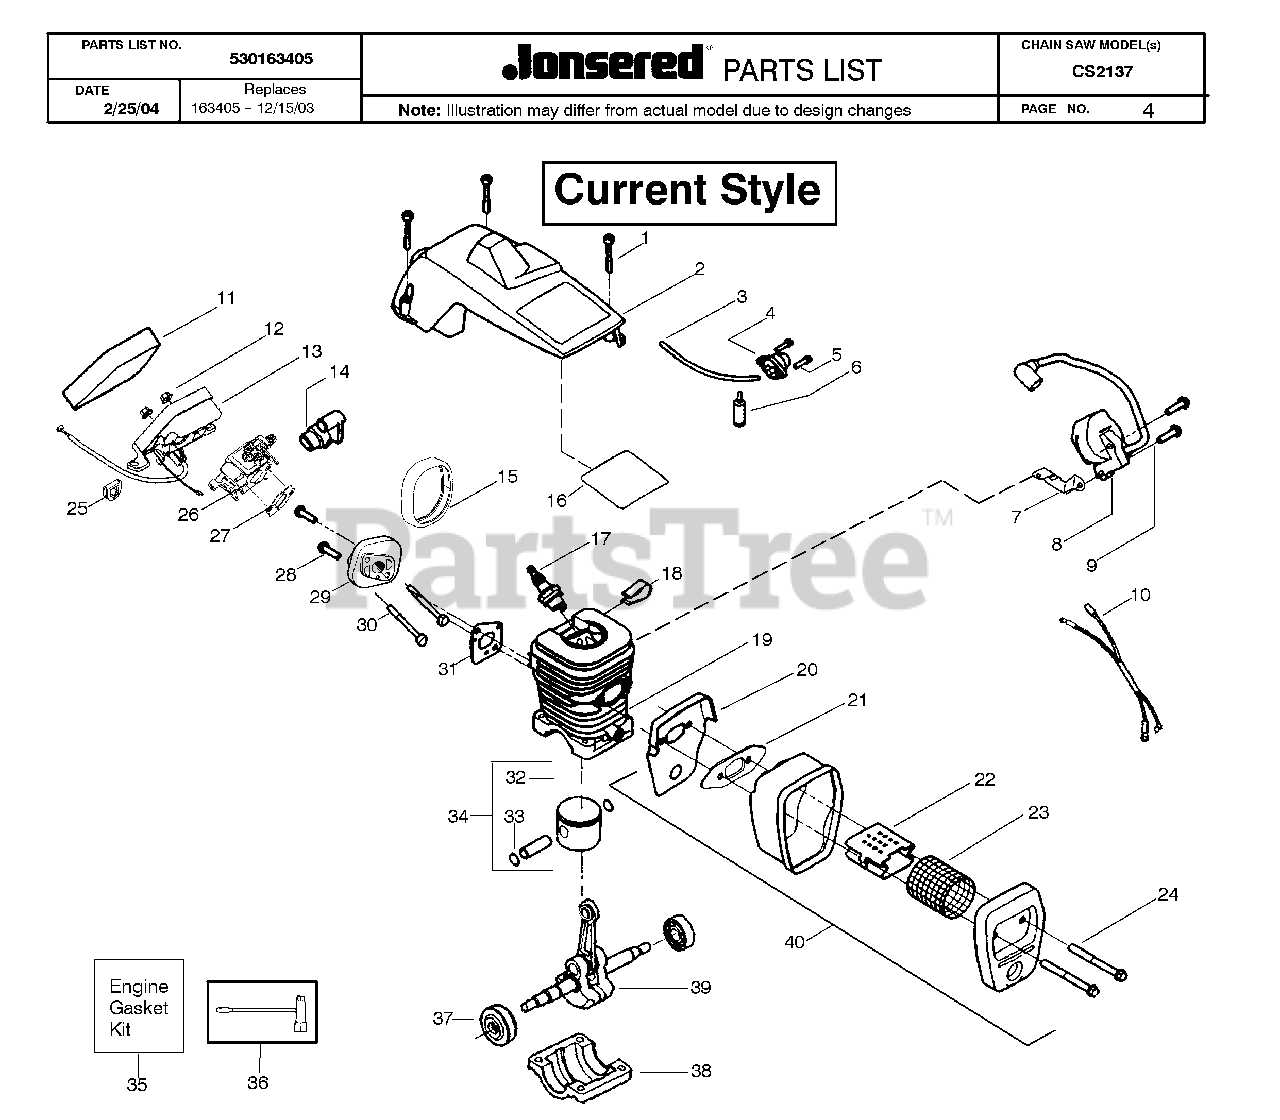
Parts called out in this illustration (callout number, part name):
2	CYL SHIELD ASSY
6	FUEL PICK-UP ASSY
7	GROUND STRAP
10	WIRE HARNESS ASSY
11	AIR FILTER
14	GROMMET-CARB ADJUST
17	SPARK PLUG (RCJ-7Y)
22	FLAME PROTECTION
29	PARTITION
32	RING-PISTON
33	C-CLIP,PSTN PIN 36/41
36	SCRENCH
37	BEARING & SEAL ASSEMBLY
39	CRANKSHAFT
40	MUFFLER
530071820	CARBURETOR
